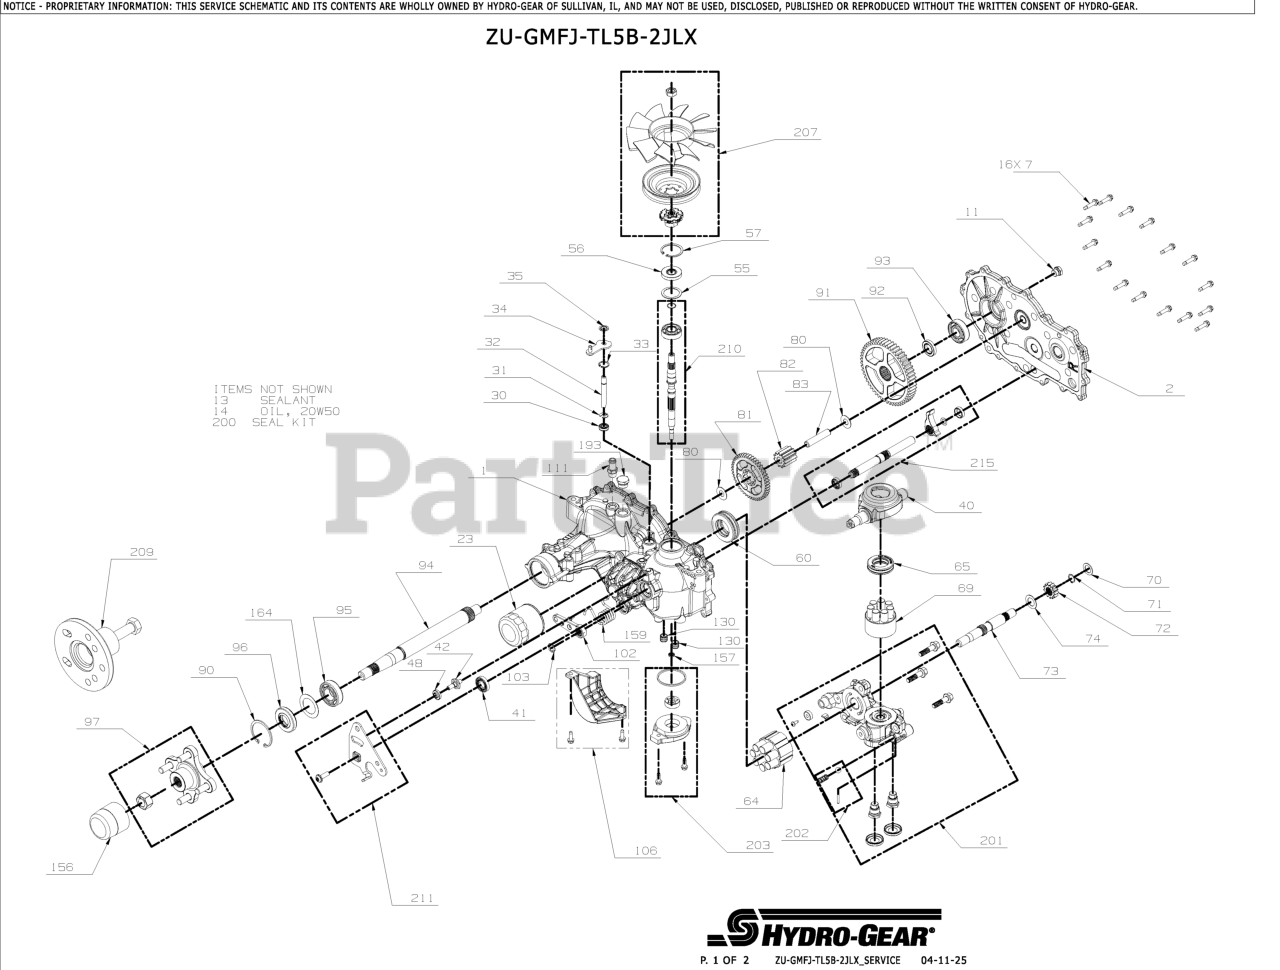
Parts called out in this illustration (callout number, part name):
1	KIT MAIN HOUSING RH, CHARGE CONTROL
2	KIT, COVER SIDE, RH
7	SCREW,HEX WASHER 1/4-20X1.125
11	PLUG, EXTERNAL HEX VENT 9/16-18
13	SEALANT TUBE 10.1OZ.
14	FLUID, HYDRO 15W50 QT
14	FLUID, HYDRO 20W50 QT
23	FILTER, HYDRO-GEAR 2800 TRANS
30	SEAL, LIP .375 X .75 X .25
31	RING. RETAINING
33	RING, RET .750
34	ARM, BYPASS
35	RING, RTNG .
40	TRUNNION, SWASHPLATE
41	SEAL, LIP 18X32X7
42	STUD. SHORT 5/16-24
48	SPACER
55	WASHER 1.23X1.56X.04
56	SEAL, LIP 17 X 40 X 7 HNBR
57	RING, RET 1.56 INT
60	HG THRUST BEARING (51462)
64	HG 16CC CYLINDER BLOCK (71579)
65	HG THRUST BLOCK (53502)
69	HG SEVEN PISTON BLOCK (71971)
70	WASHER .63X1.0X.05
71	RING, RET 62 EXT
73	SHAFT, MOTOR
74	WASHER .71 X 1.16 X .04
80	WASHER .5X1.0X.032
82	GEAR, 11T (STEEL)
83	PIN, JACKSHAFT
90	RING, RETAINING
91	GEAR, 54T
93	KIT, BEARING
94	SHAFT AXLE
95	BEARING, BALL 25.4 X 52 X 15
96	SEAL, LIP
97	KIT, HUB 4 BOLT
102	BRAKE ARM HG 71957
103	CLIP,BRAKE ARM HYDROGEAR 52027
106	KIT, FILTER GUARD
111	KIT, FITTING 1/2 BEADED 9/16
130	TUBE, CHARGE TRIPLE O-RING
156	CAP, AXLE
157	KIT, GEROTOR SEAL
159	SPRING, TORSION CCW
164	WASHER, 1.355 x 2.035 x .021 FLAT
200	HG SEAL KIT (71976)
201	KIT, CENTER SECTION RH CHARGE
202	KIT, CHARGE RELIEF
203	KIT, CHARGE PUMP
207	KIT, FAN/PULLEY
209	HUB PULLER 5 BLT HYDGEAR 72320
210	INPUT SHAFT HG 71978
211	KIT, ARM, CONTROL
215	KIT, OUTBOARD, RH ROT A / LH ROT B
